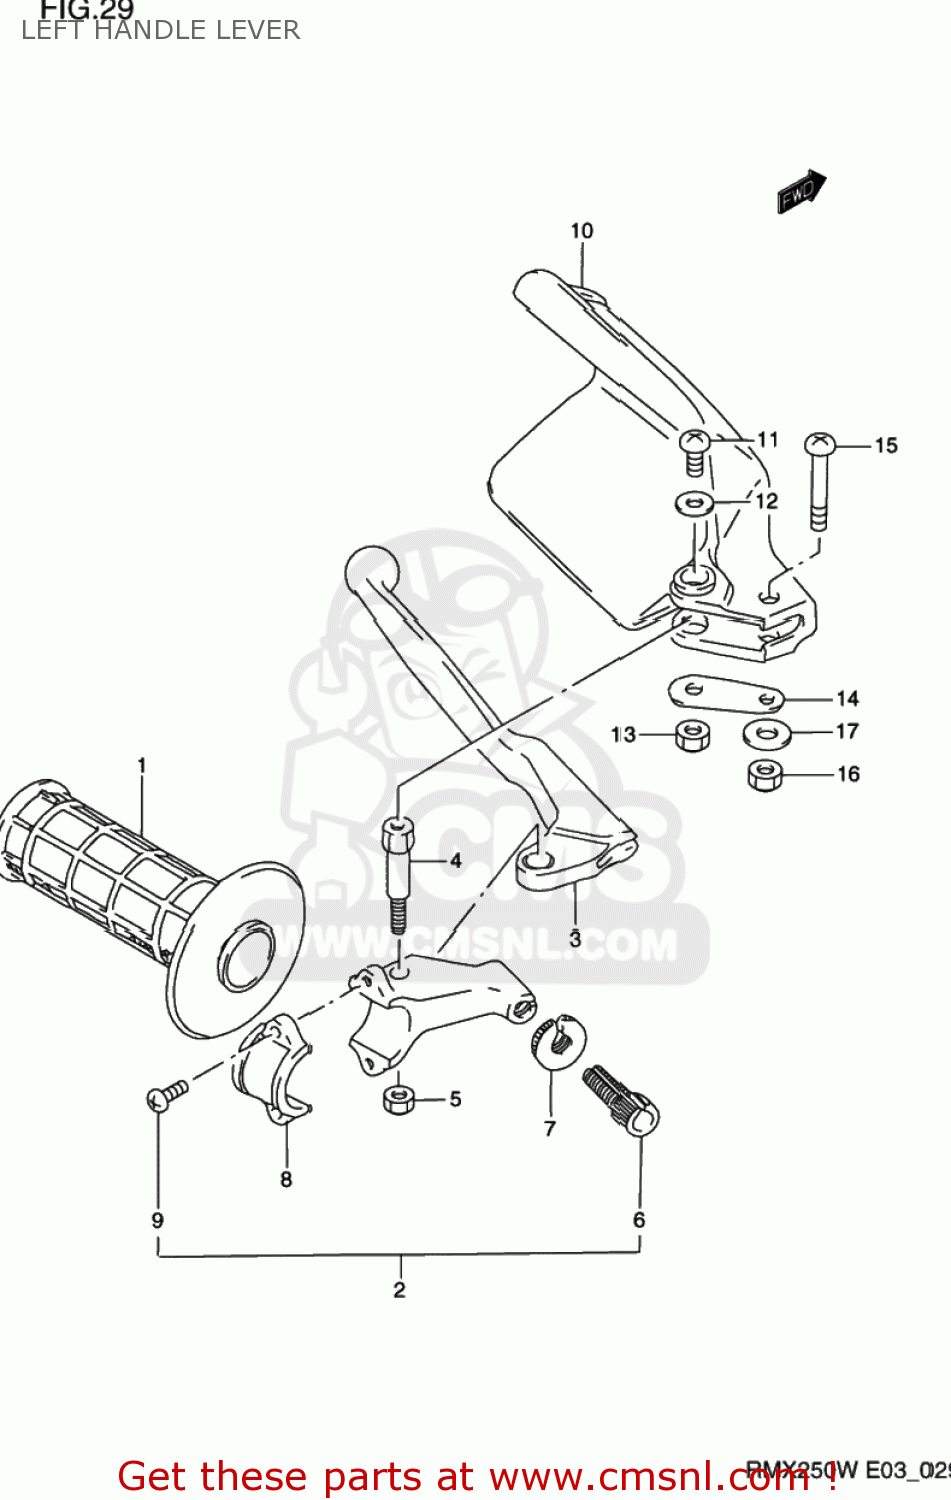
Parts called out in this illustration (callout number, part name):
1	GRIP,L
2	LEVER ASSY,CLUTCH
3	LEVER,CLUTCH
4	BOLT,LEVER SET
5	NUT 6MM
6	ADJUSTER,CABLE
7	NUT,LOCK
8	BRACKET,CLUTCH LEVER HOLDER
9	SCREW(5X14)
10	COVER,KNUCKLE,L
11	SCREW
12	WASHER(5.5X16X1.2)
13	NUT 6MM
14	PLATE,KNUCKLE COVER,L LWR
15	SCREW(6X35)
16	NUT 6MM
17	WASHER(6.5X16X1.6)
